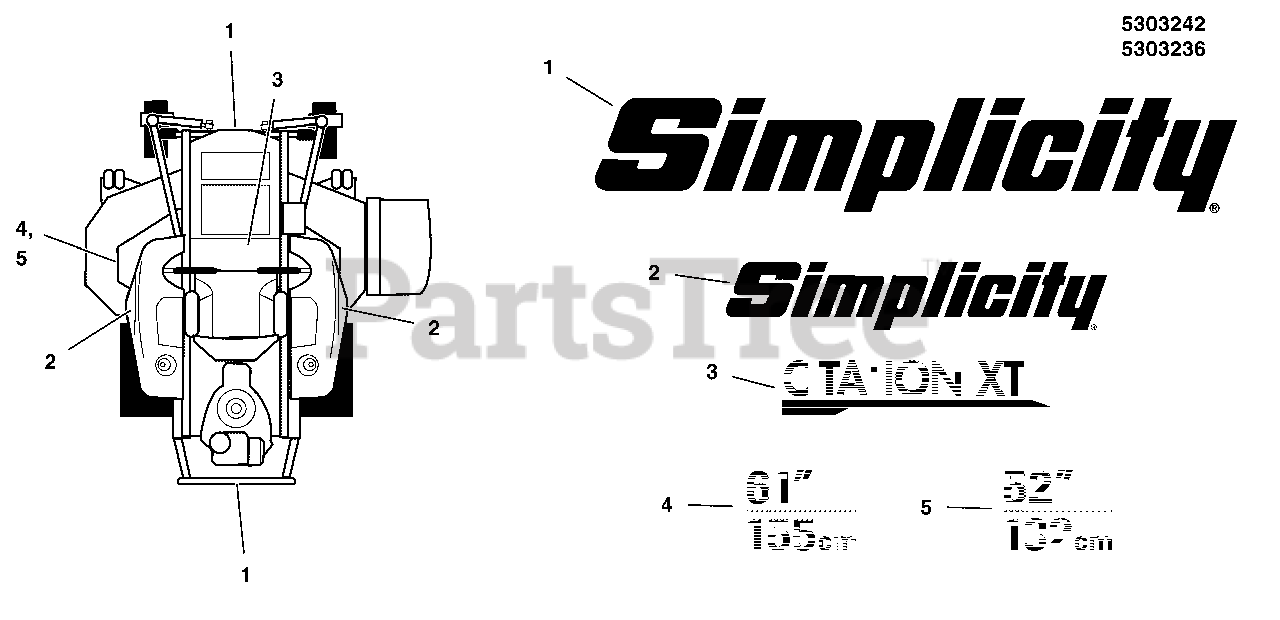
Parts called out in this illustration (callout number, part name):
1	DECAL, Model, SMI Logo 10.47" Long
2	DECAL, Simplicity
3	DECAL, SMI, Model Citation XT
4	DECAL, MOWER WIDTH 61IN/155CM
5	DECAL, 52"/132cm
